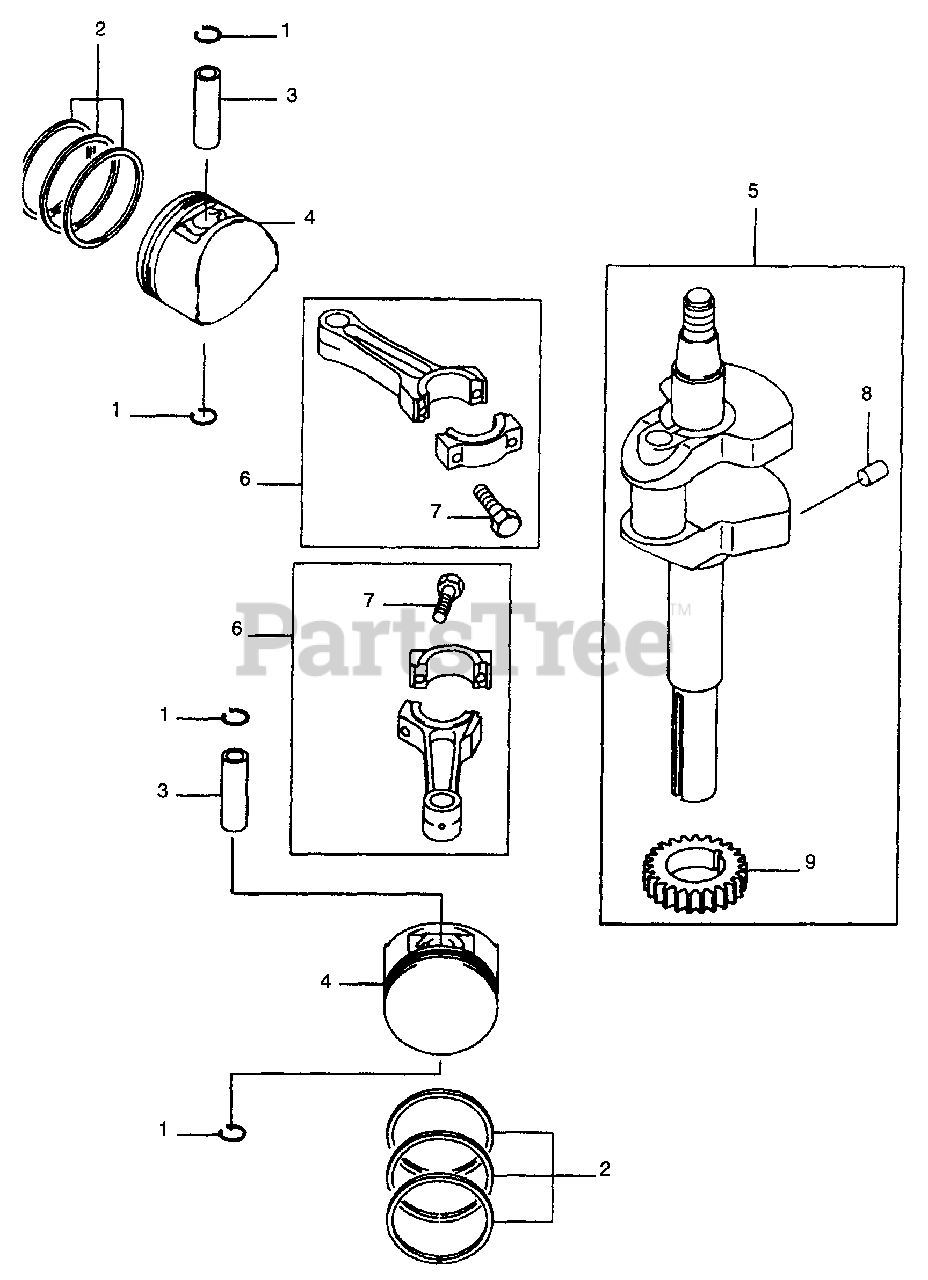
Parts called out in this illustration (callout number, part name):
2	Set Piston Ring
4	Engine Piston
5	Crankshaft Ass'y
6	Connecting Rod Assy
